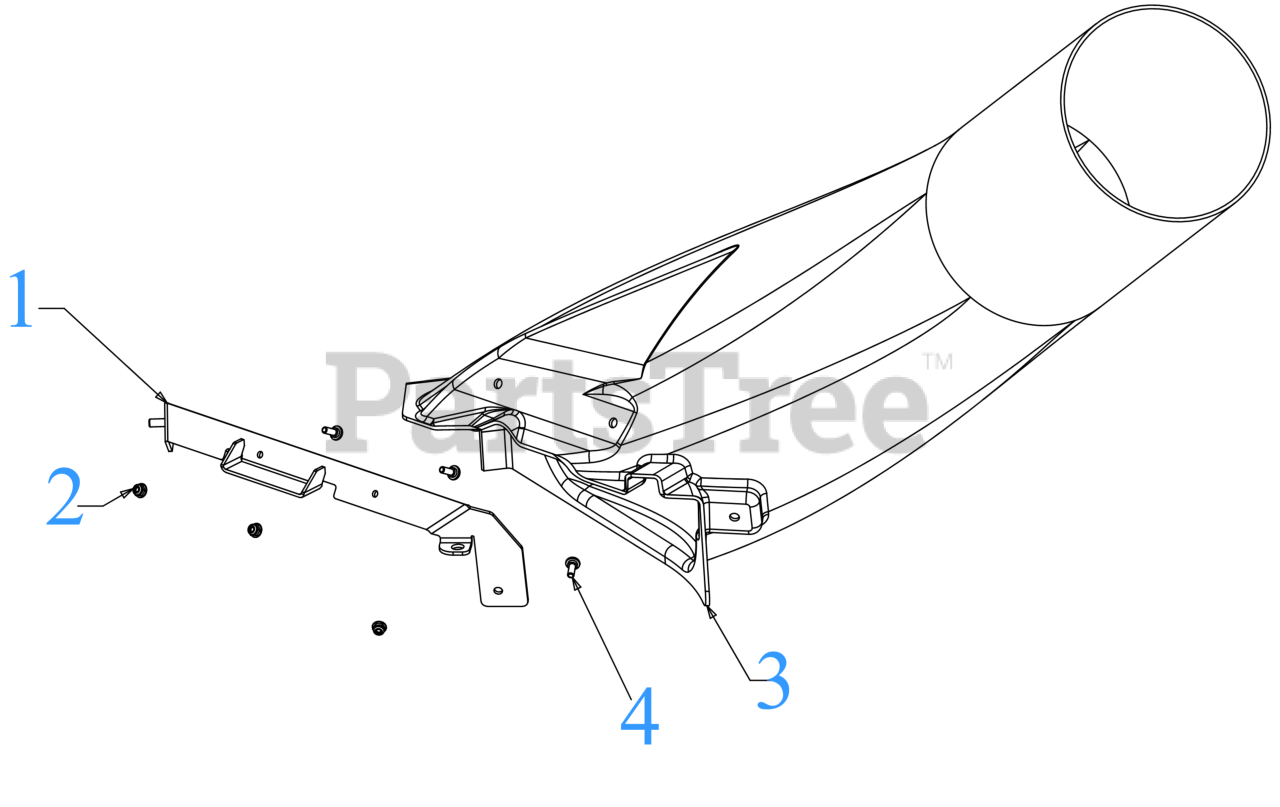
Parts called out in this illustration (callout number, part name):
1	CHUTE BRACKET
2	FLANGE LOCK NUT
3	BAGGER DISCHARGE CHUTE 54"/60"
4	SCREW-SHLDR 1/4-20 x .75 TORX
